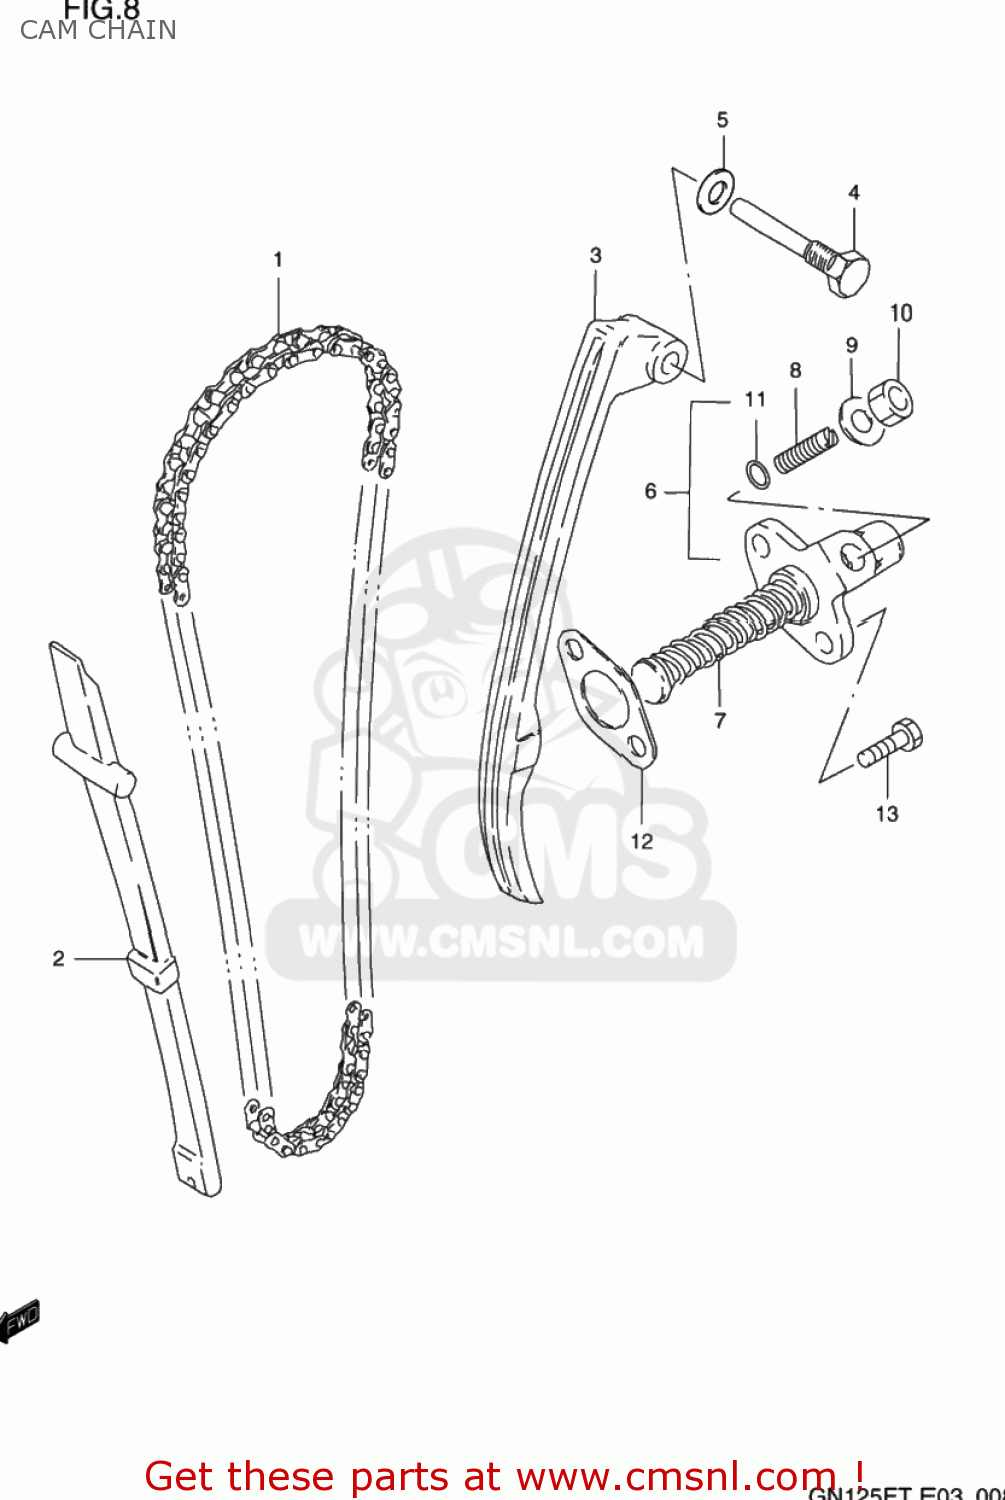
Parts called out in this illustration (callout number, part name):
1	CHAIN,CAMSHAFT DRIVE
2	GUIDE,CAM CHAIN
3	TENSIONER,CAM CHAIN
4	BOLT,CAM CHAIN TENSIONER
5	GASKET 8.2X14X1 (NAS)
6	ADJUSTER ASSY,TENSIONER
7	SPRING
8	SCREW
9	WASHER
10	NUT
11	O RING(D:1.9,ID:5.7)
12	GASKET,TENSIONER ADJUSTER (NAS)
13	BOLT
